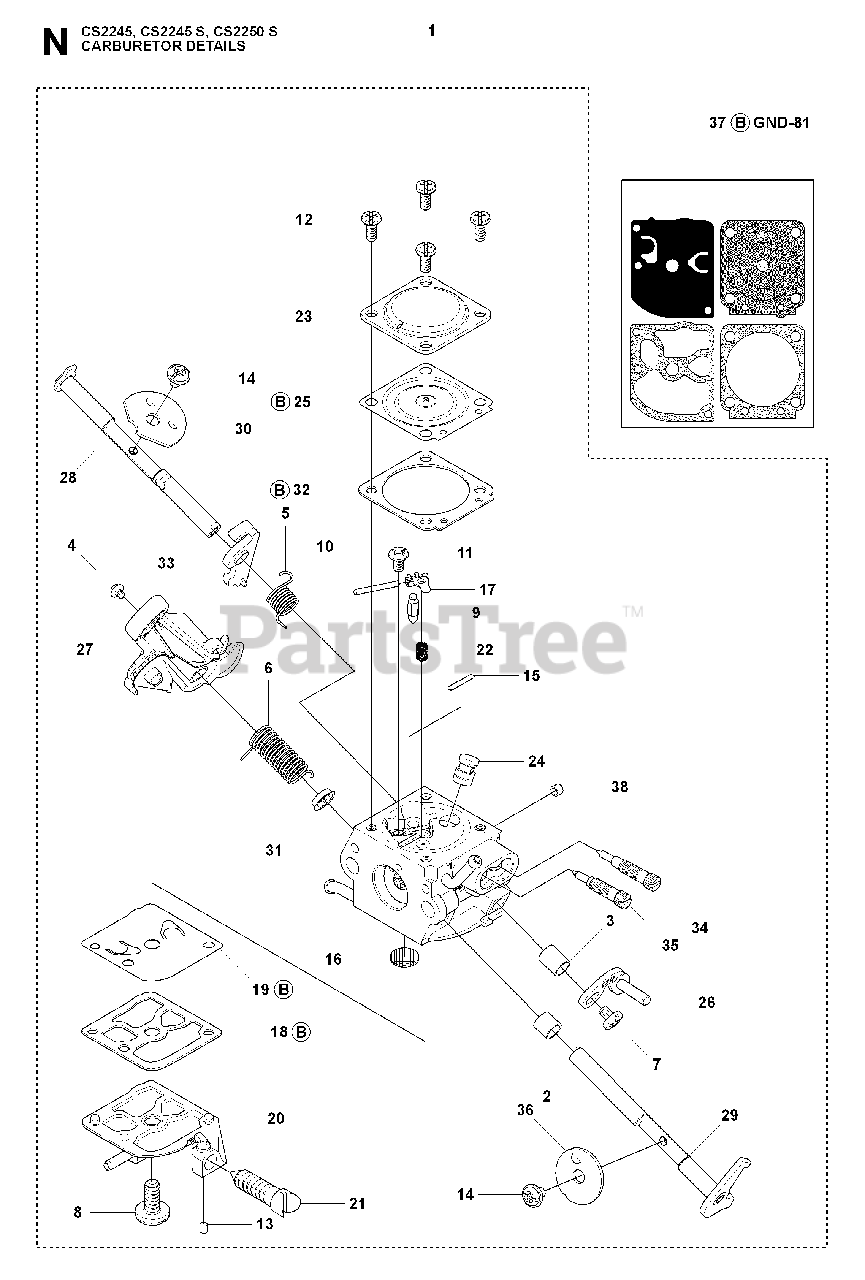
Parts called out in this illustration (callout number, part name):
1	CARBURETOR
9	INLET NEEDLE
10	PIN FULCRUM
19	PUMP DIAPHRAGM
25	DIAPHRAGM
27	THROTTLE LEVER
28	SHAFT ASSY
29	SHAFT ASSY
37	GASKET KIT
